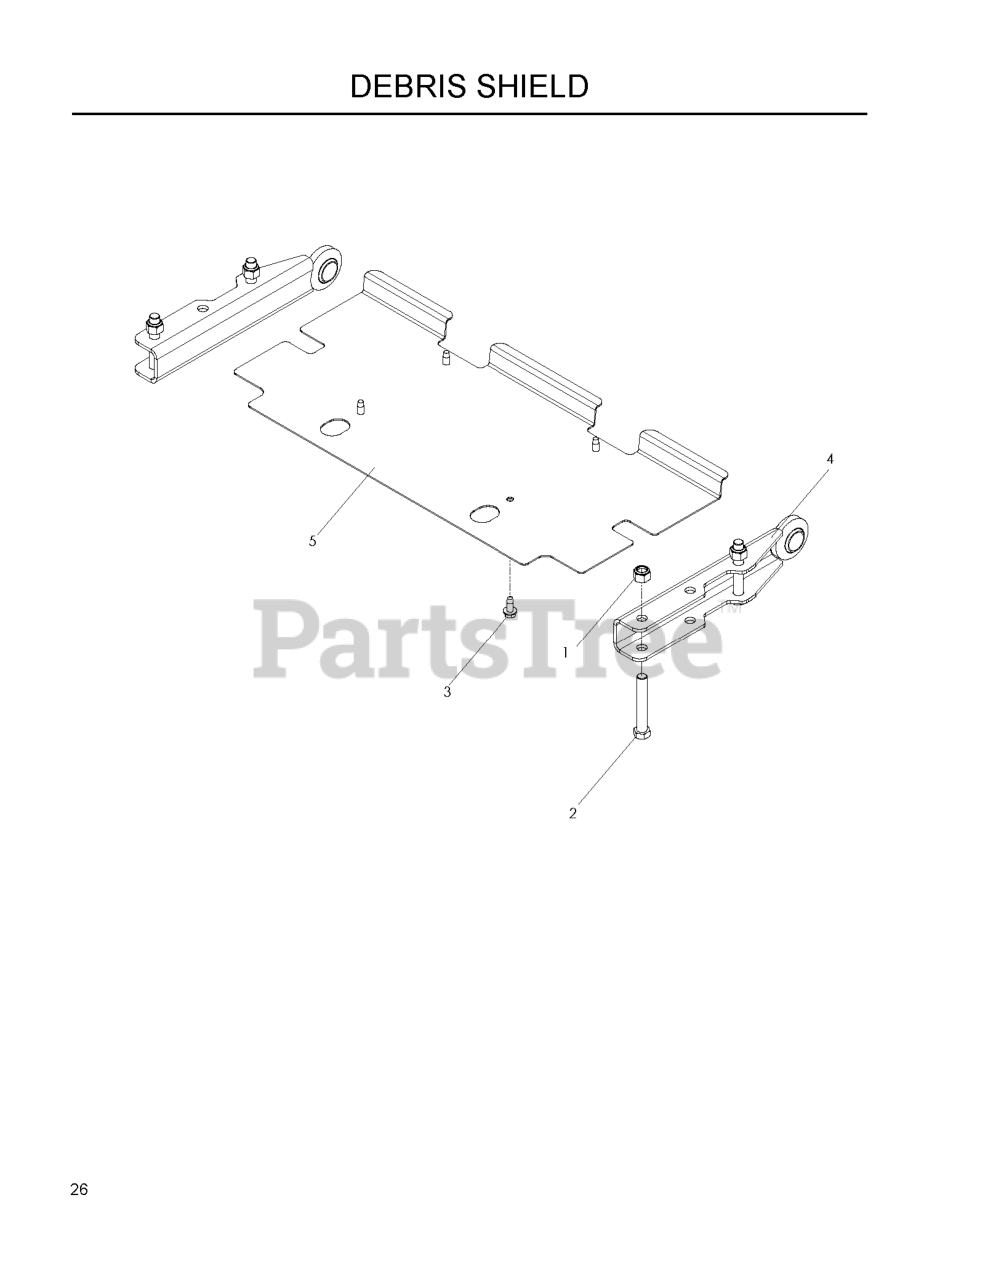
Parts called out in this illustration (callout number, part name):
1	NUT 1/2-13 HEX NYLOC ZD
2	HCS 1/2C X 3 1/4
3	BOLT 5/16-18 X 3/4
4	STRUT WELDMENT, REAR
5	REAR DEBRIS SHIELD
